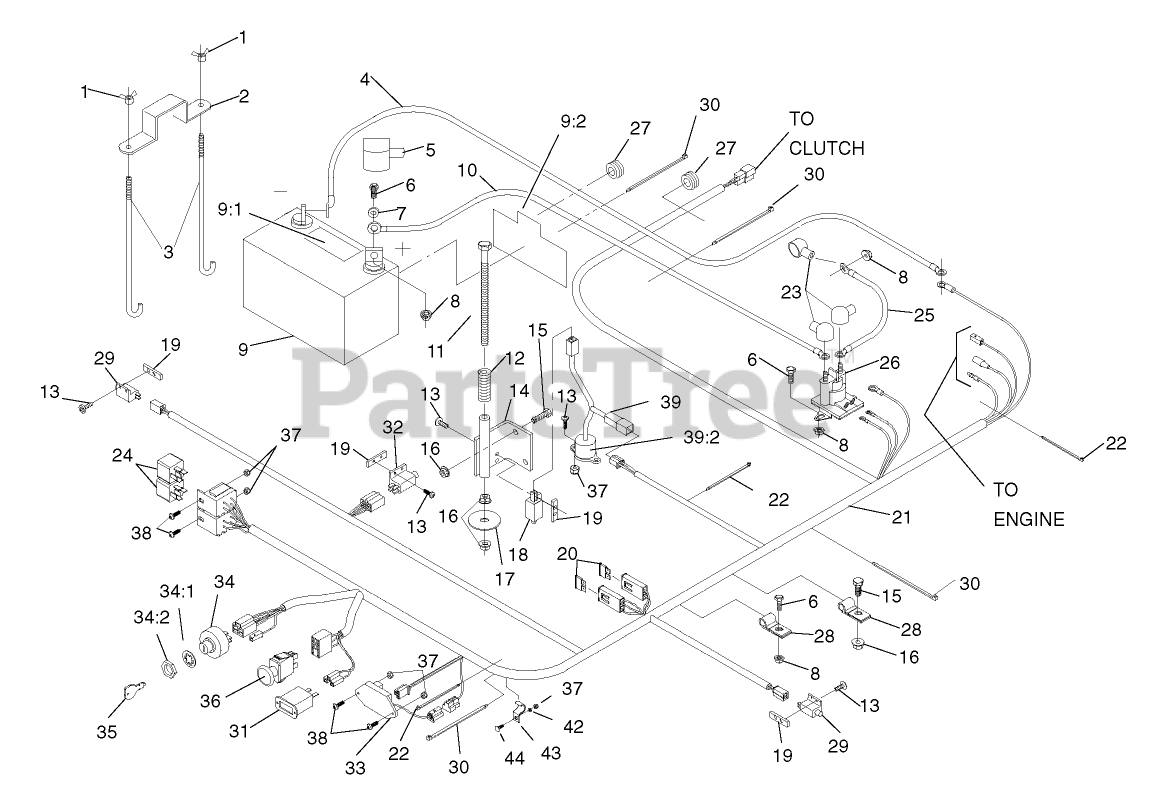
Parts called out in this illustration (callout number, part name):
1	WINGNUT
2	STRAP-HOLDDOWN
3	BOLT-HOLDDOWN
4	CABLE-GROUND, NEGATIVE
5	INSULATOR-BATTERY
6	SCREW-HH
7	WASHER-FLAT
8	NUT-HF
9	BATTERY
9:1	Decal-Battery
9:2	Decal-Battery
10	CABLE-BATTERY, POSITIVE
11	SCREW-HH
12	SPRING-SWITCH, SEAT
13	SCREW-PPH
14	BRACKET-SWITCH, SEAT
15	SCREW-HH
16	NUT-HF
17	WASHER
18	SWITCH-CLOSED, NORMALLY
19	PLATE-TAPPED
20	FUSE-BLADE TYPE, 20 AMP
21	HARNESS-WIRE
22	TIE-CABLE
23	INSULATOR-SOLENOID
25	CABLE-STARTER, POSITIVE
26	SWITCH-SOLENOID
27	GROMMET
28	CLIP-LOOM
29	SWITCH-OPEN, NORMALLY
30	TIE-PLASTIC
31	METER-HOUR
32	SWITCH
33	MODULE-DELAY, SEAT
34	Key Switch ASM
34:1	WASHER-TOOTH, INTERNAL
34:2	NUT-HH
35	KEY-IGNITION
36	SWITCH-DELTA
37	NUT-LOCK, NI
38	BOLT-CARR
39	TILT SWITCH ASM
39:2	DECAL-SWITCH, MERCURY
42	WASHER-FLAT
43	CLIP-HALF, LOOM
44	BOLT-CARR
